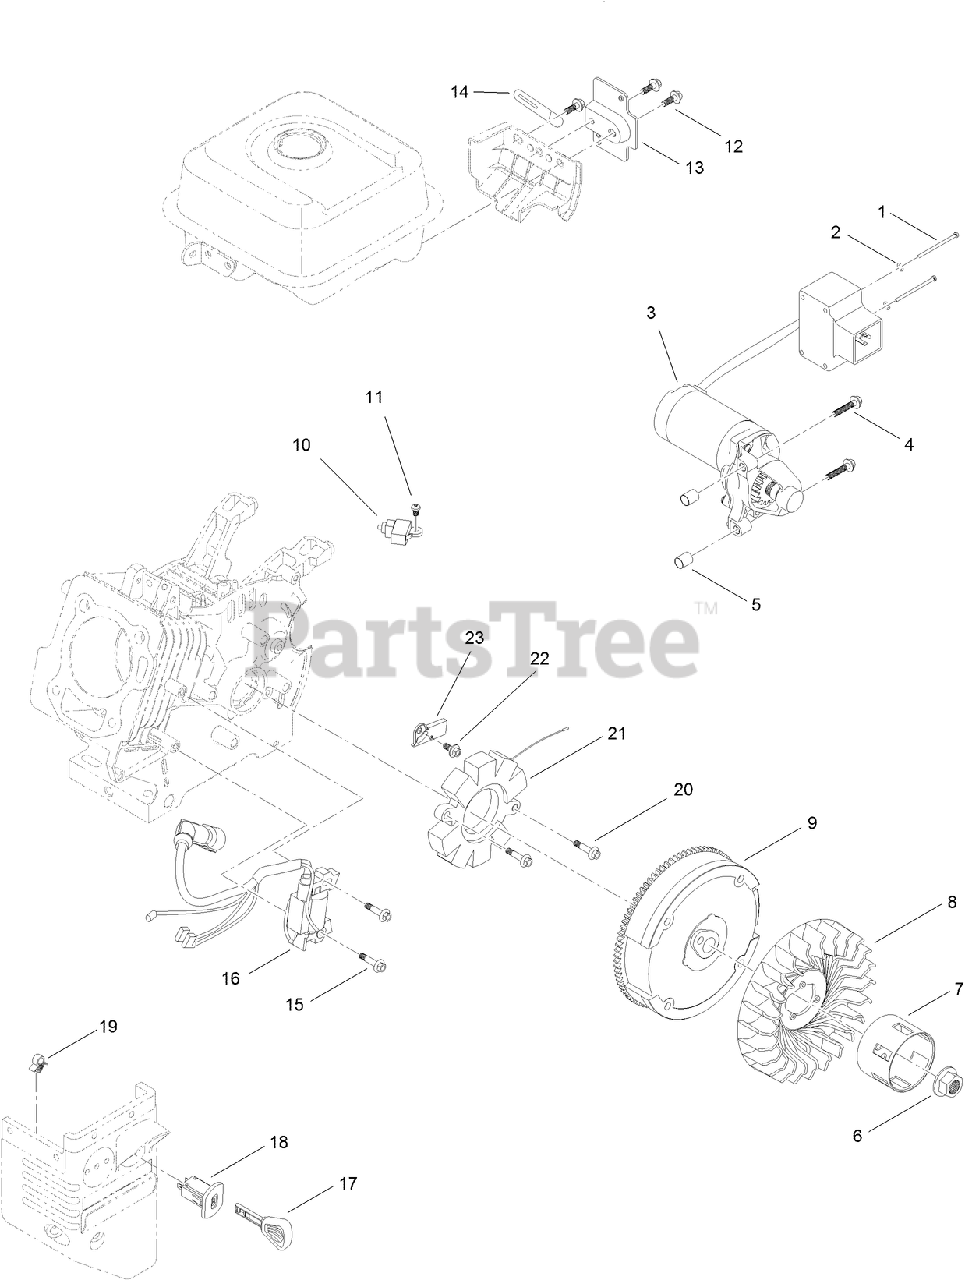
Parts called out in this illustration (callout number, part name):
1	SCREW-BHP
2	WASHER-PLAIN
4	SCREW-FLANGE
5	PIN-DOWEL
6	NUT-FLANGE
7	CUP-STARTER
8	FAN-COOLING
9	FLYWHEEL ASM
10	SWITCH-KILL, ENGINE
11	SCREW-PPH
12	SCREW-HHF
13	BRACKET-SWITCHBOX, STARTER
14	CLIP-HARNESS, WIRE
15	SCREW-HHF
18	SWITCH-KEY
20	SCREW-HHF
21	ALTERNATOR
22	SCREW-HHF
23	CLAMP-WIRE, CHARGE
